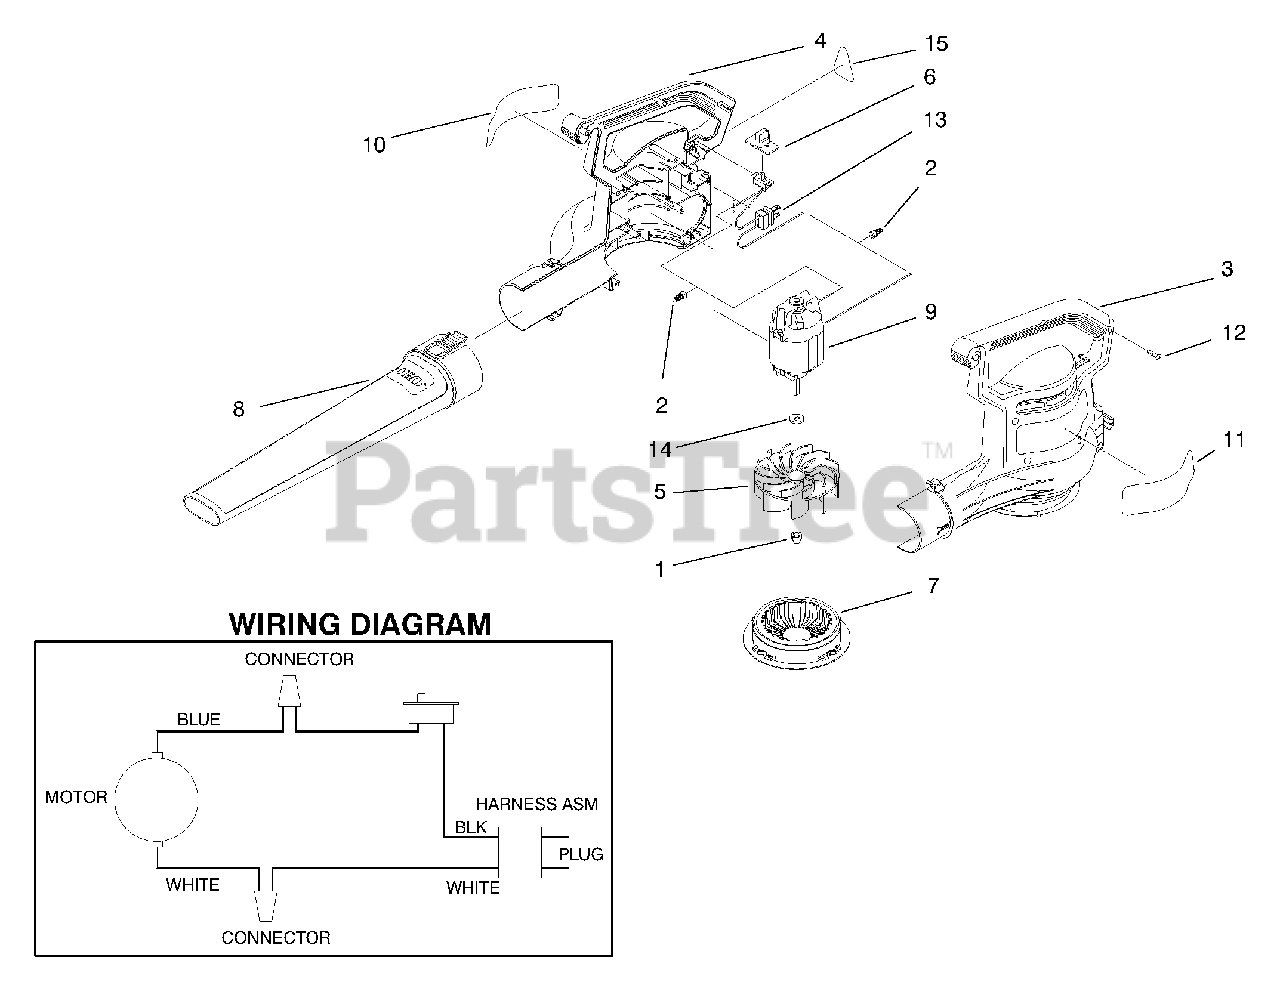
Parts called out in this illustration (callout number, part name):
1	Nut-Hex Lock
2	Connector-Wire Nut
3	Housing-LH
4	Housing-RH
5	Impeller
6	Cover-Switch
7	Cover-Inlet
8	Tube-Blower
10	Decal-Logo
11	Decal-Label
13	Harness Assembly
15	Decal-Information
